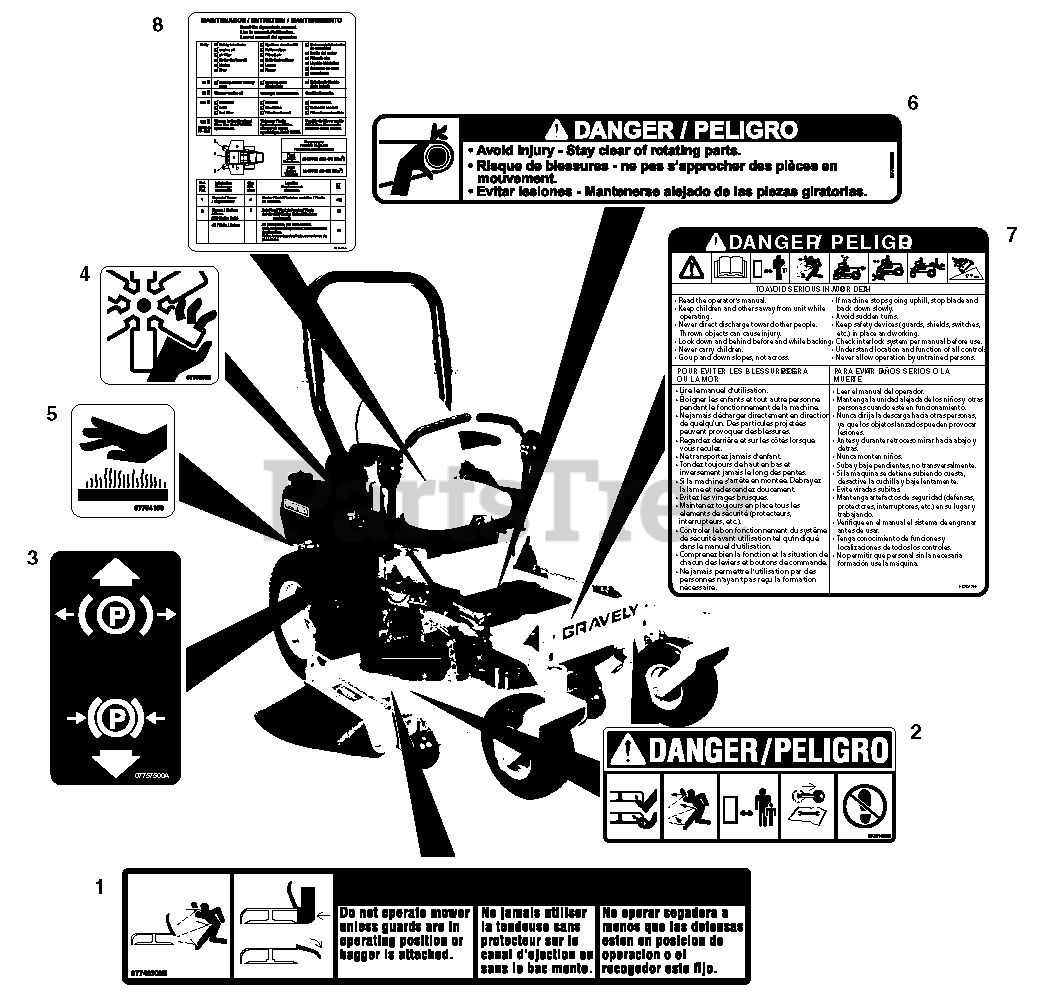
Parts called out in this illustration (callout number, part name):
1	Decal, Warning
2	Decal, Mower Pan Head Danger
3	Decal, Parking Brake Lever
4	Decal, Danger Fan
5	Decal, Hot Surface
6	Decal, Danger Rotating Parts
7	Decal, Danger- Bilingual
8	Decal, Maintenance Instructions
